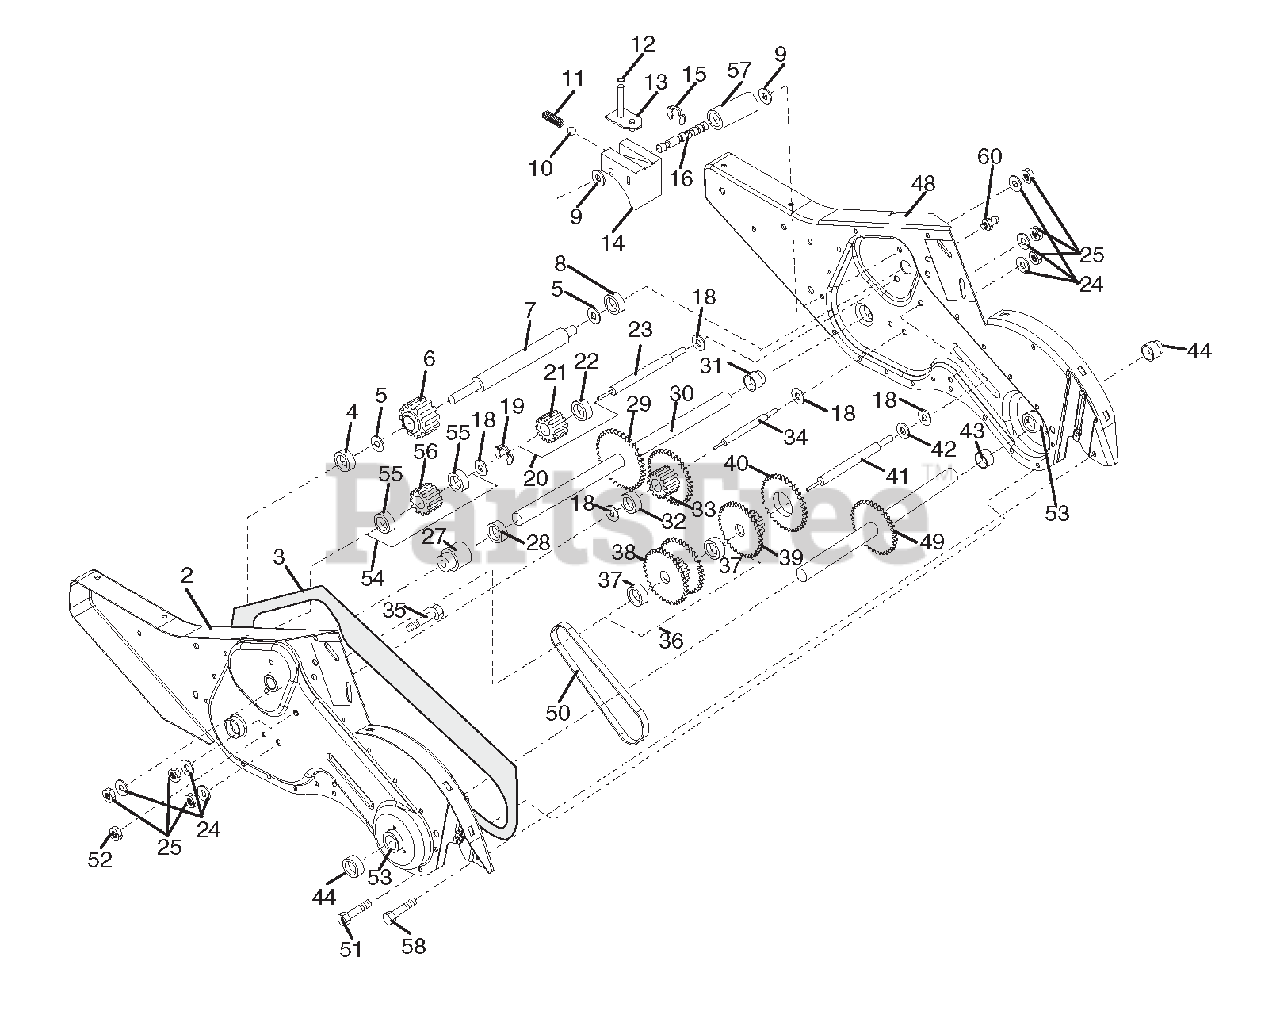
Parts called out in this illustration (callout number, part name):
1	Transmission Assembly (Include
2	Gearcase, LH w/Bearing (Includ
3	Gasket, Gearcase
4	Bearing, Needle
5	Washer, Thrust 5/8 x 1.10 x 1/
6	Pinion, Input
7	Shaft, Input
8	Bearing, Needle
9	Washer, Seal
10	Ball, Steel
11	Spring, Shift, Fork
13	Arm, Shift
14	Fork, Shift
15	Ring, Klip
16	Shaft, Shift
19	Ring, Klip
20	Gear, Assembly, Reverse Idler
21	Gear, Reverse Idler
22	Bearing, Needle
23	Shaft, Reverse Idler
24	Washer, Lock 7/16
25	Nut, Hex 7/16-20
27	Bearing, Shaft, Ground Drive L
28	Spacer 0.765 x 1.125 x 1.23
29	Chain #35-50 Pitch
30	Ground Shaft Assembly
31	Bearing, Shaft, Ground Drive R
32	Spacer 0.70 x 1.00 x 1.150
33	Sprocket and Gear Assembly
34	Shaft, Reduction (2nd)
35	Screw, Whiz, Lock 5/16-18 x 3-
36	Sprocket Assembly w/Bearing (I
37	Bearing, Needle
38	Sprocket, Tine
39	Gear, Cluster, Red 1st & 2nd
40	Gear, Reverse
41	Shaft, Reduction (1st)
42	Washer, Thrust
43	Spacer 1.01 x 1.75 x 0.760
44	Seal Asm. Oil
48	Gearcase, RH w/Bearing (Includ
49	Shaft, Tine
50	Chain, Roller #50-50 Pitch
51	Screw 1/4-20 x 1/2
52	Nut, Hex 5/16-18
53	Bearing Kit, Tine Shaft
54	Gear, DRT Idler w/Bearing (Inc
55	Bearing, Needle
56	Gear, DRT Idler
57	Spacer, Split .52 x .64 x 1.04
58	Screw 1/4-20 x .875
60	Fitting Grease
